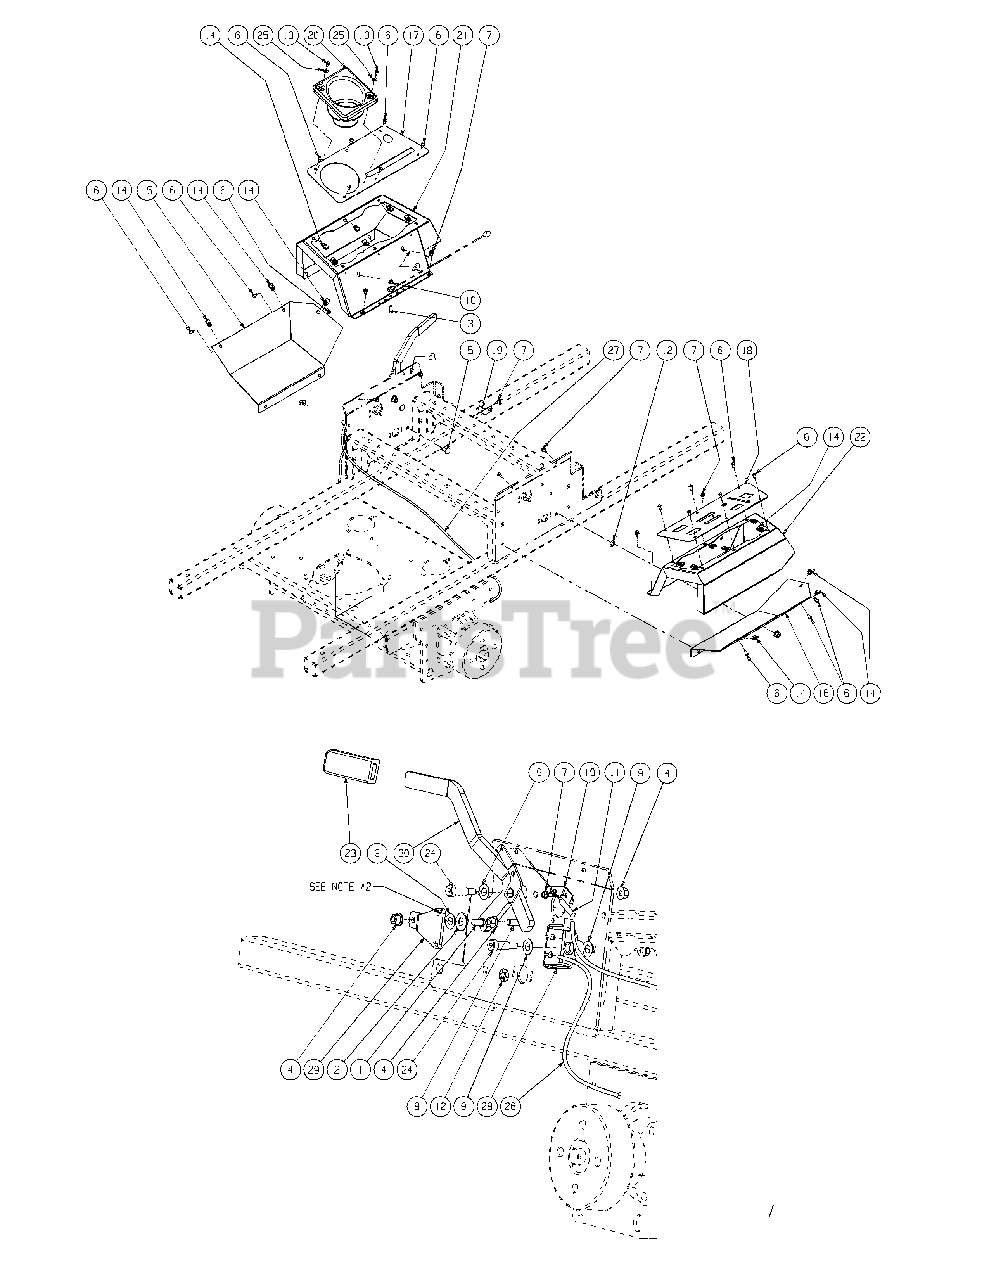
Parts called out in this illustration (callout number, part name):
1	Shoulder Bolt, 1/2 x 1/2
2	Washer, 1/2 Zinc
3	Screw, Hex, Cap, 1/4-20 x .75
4	Flange Lock Hex Nut, 3/8-16
5	Carriage Bolt, 3/8-16 x .75
6	Screw Button Head, 1/4-20 x .5
7	Screw, TT, 1/4-20, 0.5, Hex Index Washer
8	Carriage Bolt, 3/8-16, 1.00
9	Washer, .508 ID x 1.0 OD x .020
10	Hex Flange Lock Nut, 1/4-20
11	Left Hand Brake Cable
12	Push Retainer, 3/8
13	Screw, #10-32 x 0.500
14	U-Nut, 1/4-20
15	Lower Panel, LH
16	Lower Panel, RH
17	Control Panel Cover, LH
18	Control Panel Cover, RH
19	Brake Cable Mounting Bracket
20	Cup Holder
21	Control Panel, LH
22	Control Panel, RH
23	Parking Brake Grip
24	Shoulder Bolt, 1/2 x 1.00, 3/8-16
25	Washer, 3/16
26	Brake Cable, LH
27	Brake Cable, RH
28	Brake Cable Bracket
29	Centering Bracket
